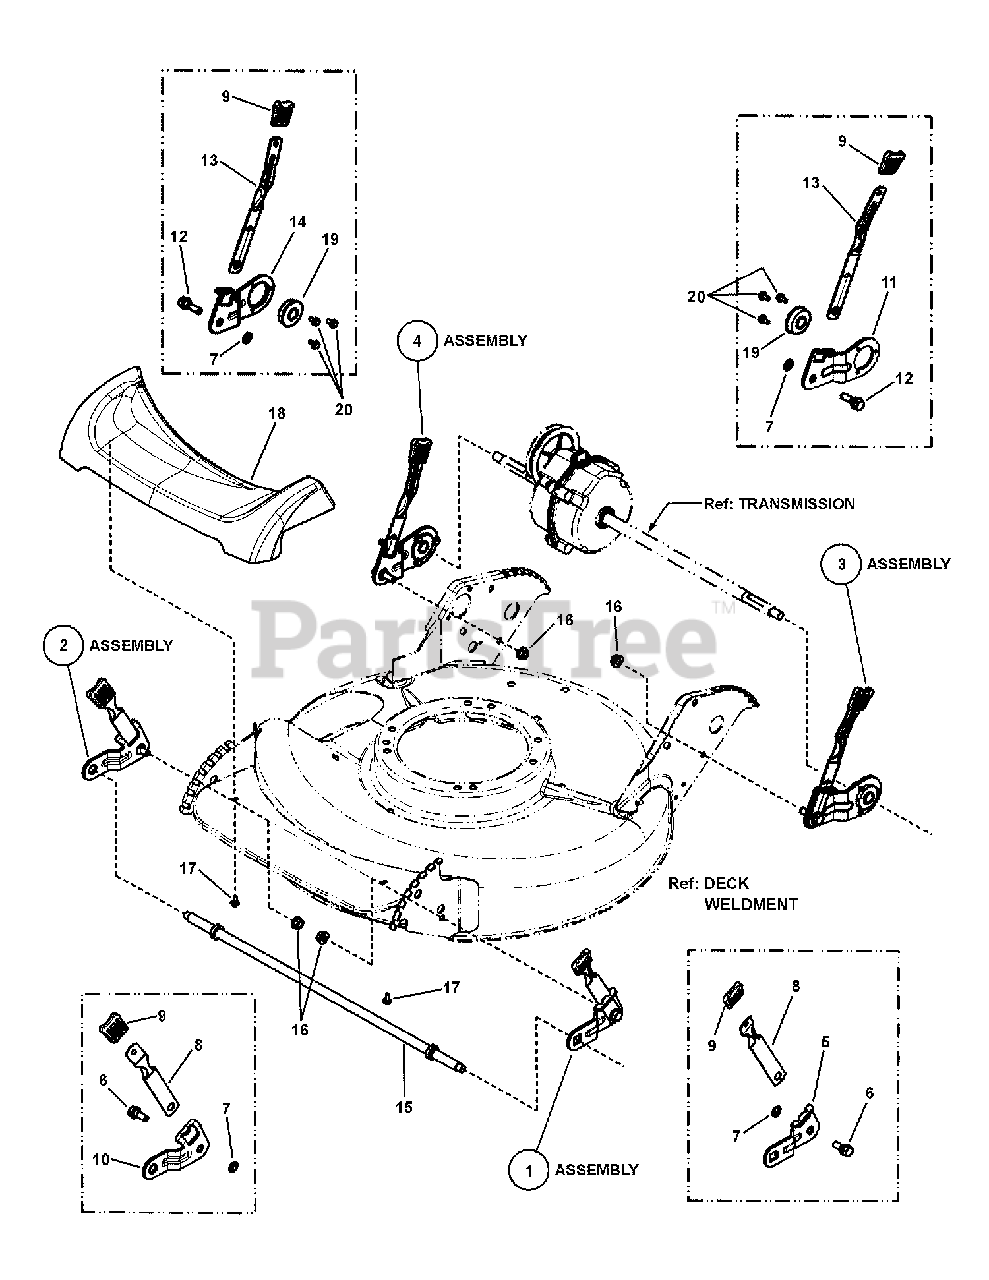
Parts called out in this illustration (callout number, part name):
1	ASSEMBLY, Front Left Wheel Arm (.512" Square Hole)
1	ASSEMBLY, Front Left Wheel Arm (.453" Square Hole)
2	ASSEMBLY, Front Right Wheel Arm
3	ASSEMBLY, Wheel Arm Left Rear Long SP21S
4	ASSEMBLY, Wheel Arm, Right Rear (S.P.)
5	WHEEL ARM, L.H. Front (.512" Square Hole)
5	WHEEL ARM, L.H. Front (.453" Square Hole)
6	BOLT, 5/16-18 x 3/4" Hex Washer Face Shoulder
7	RETAINER, 5/16" Bolt
8	LATCH, Height
9	GRIP, Height Latch - Black (1.3" Wide)
10	WHEEL ARM, R.H. Front (Round Hole)
11	ARM, Wheel, Left Rear
12	BOLT, 5/16-18 x 1" Hex Washer Face Shoulder
13	LATCH, Height Adjusting (long)
14	ARM, Wheel, Right Rear
15	AXLE, Front, Easy Line (3/8-16 Threads)
15	AXLE, Front, (7/16-20 Threads)
16	NUT, 5/16-18 Hex Flange Lock, GR 5
17	SCREW, Round Washer Head Torx, Hi-Lo
18	COVER, Front 21" walk
19	BEARING, 9/16" I.D.
20	SCREW, #10-32 x 3/8" Hex Washer Self-Tap
